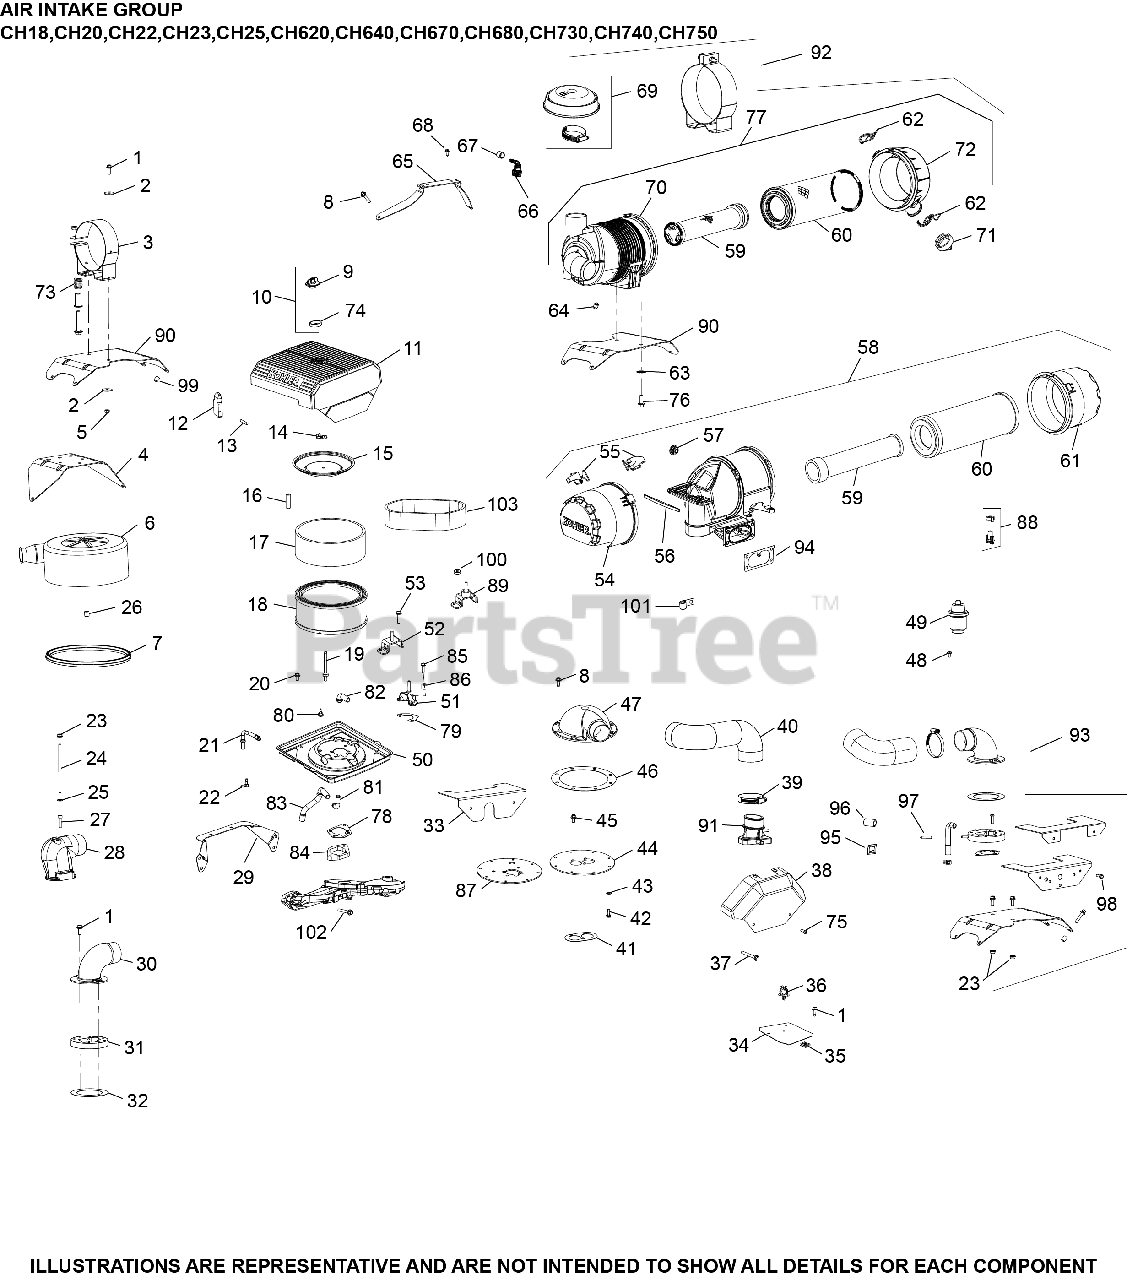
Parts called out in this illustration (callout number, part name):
9	KNOB, COVER
10	KIT, KNOB W/SEAL
11	COVER, AIR CLEANER
11	KIT, AIR CLEANER COVER
14	NUT, WING
15	COVER, INNER AIR CLEANER
16	SEAL, BREATHER
17	PRE-CLEANER (HIGH)
18	ELEMENT, AIR FILTER (HIGH) - Also available Retail Packaged 24 883 03-S1 Air Filter Kit
20	SCREW, FLG THD FRM M6X1.0X16
21	HOSE, EVAP
22	CONNECTOR, EVAPORATIVE HOSE
29	BRACKET, AIR CLEANER BASE
48	SCREW, THREAD FORMING
50	KIT, AIR CLEANER BASE
52	BRACKET, AIR CLEANER
78	GASKET, AIR CLEANER BASE
